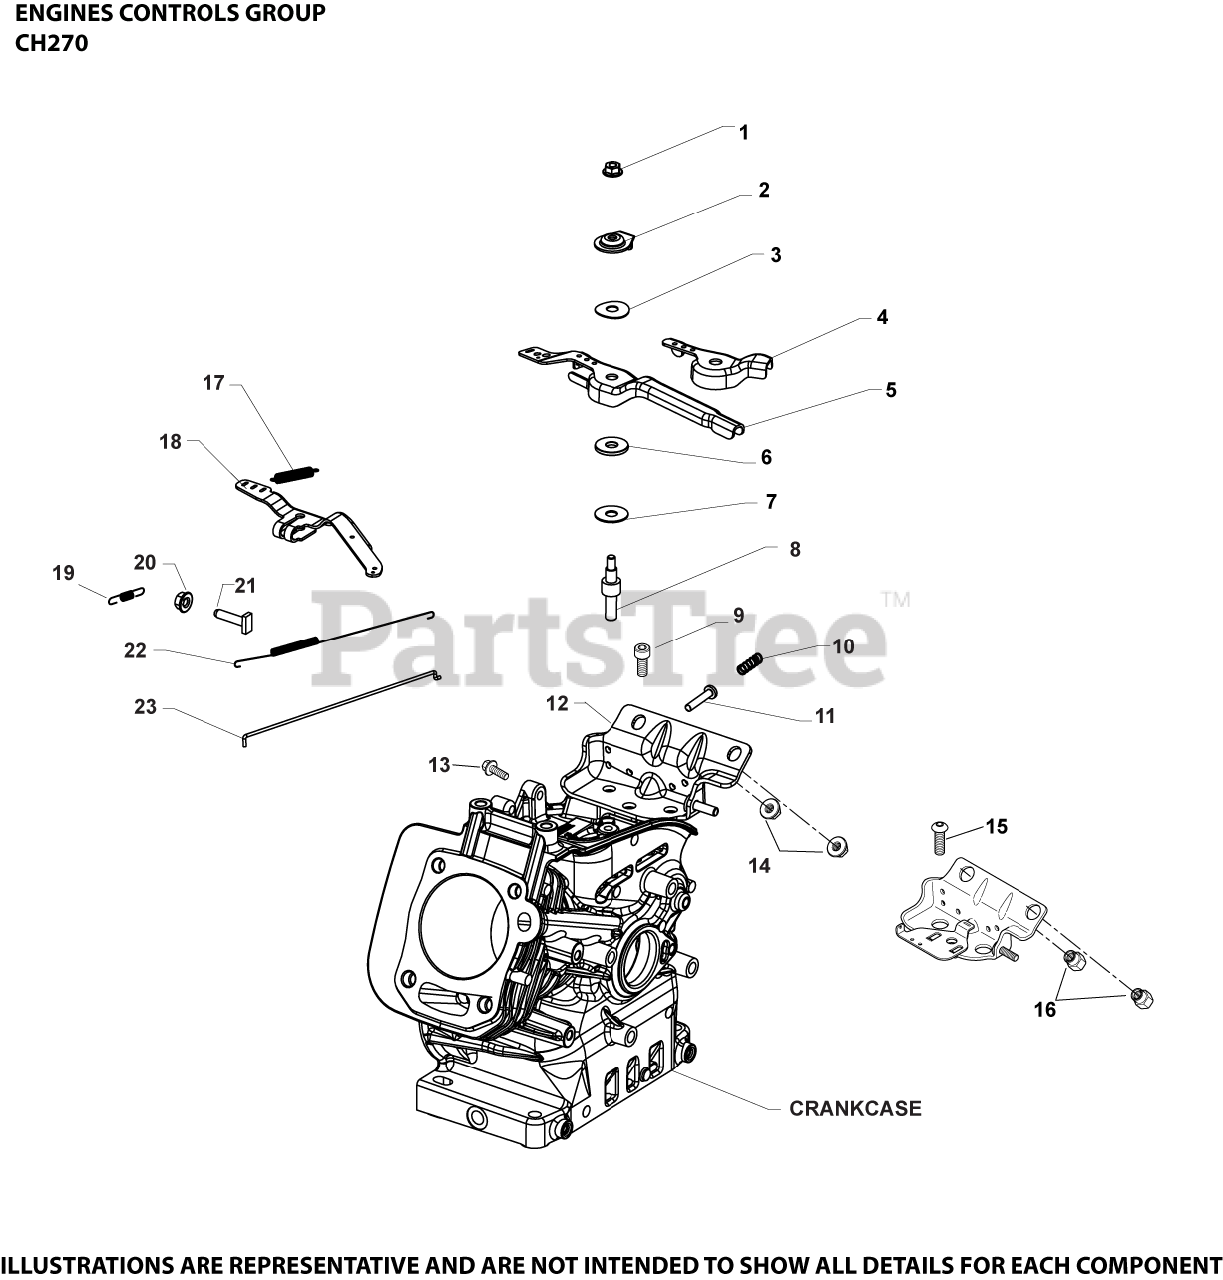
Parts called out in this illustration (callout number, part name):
1	NUT, HEX FLANGE LOCK (M6)
2	WASHER, CONTROL LEVER
3	WASHER, SPRING
5	LEVER, CONTROL THROTTLE
6	WASHER, NYLON CONTROL LEVER
7	WASHER, FLAT
8	STUD, CONTROL LEVER
9	SCREW, HEX SOCKET HD CAP (CKY)
10	SPRING, COMPRESSION
11	SCREW, SPEED ADJUSTING
12	BRACKET, FUEL AND CONTROLS
13	SCREW, M6 X18
14	NUT, FLG M8X1.25
17	SPRING, THROTTLE RETURN
18	KIT, GOVERNOR LEVER
19	SPRING, GOVERNOR
20	NUT, HEX FLANGE (M6) - USE 14 100 16-S
20	NUT, FLG M6X1.0
21	SCREW, RECTANGLE HEAD (M6)
22	SPRING, LINKAGE
23	LINKAGE, GOVERNOR
